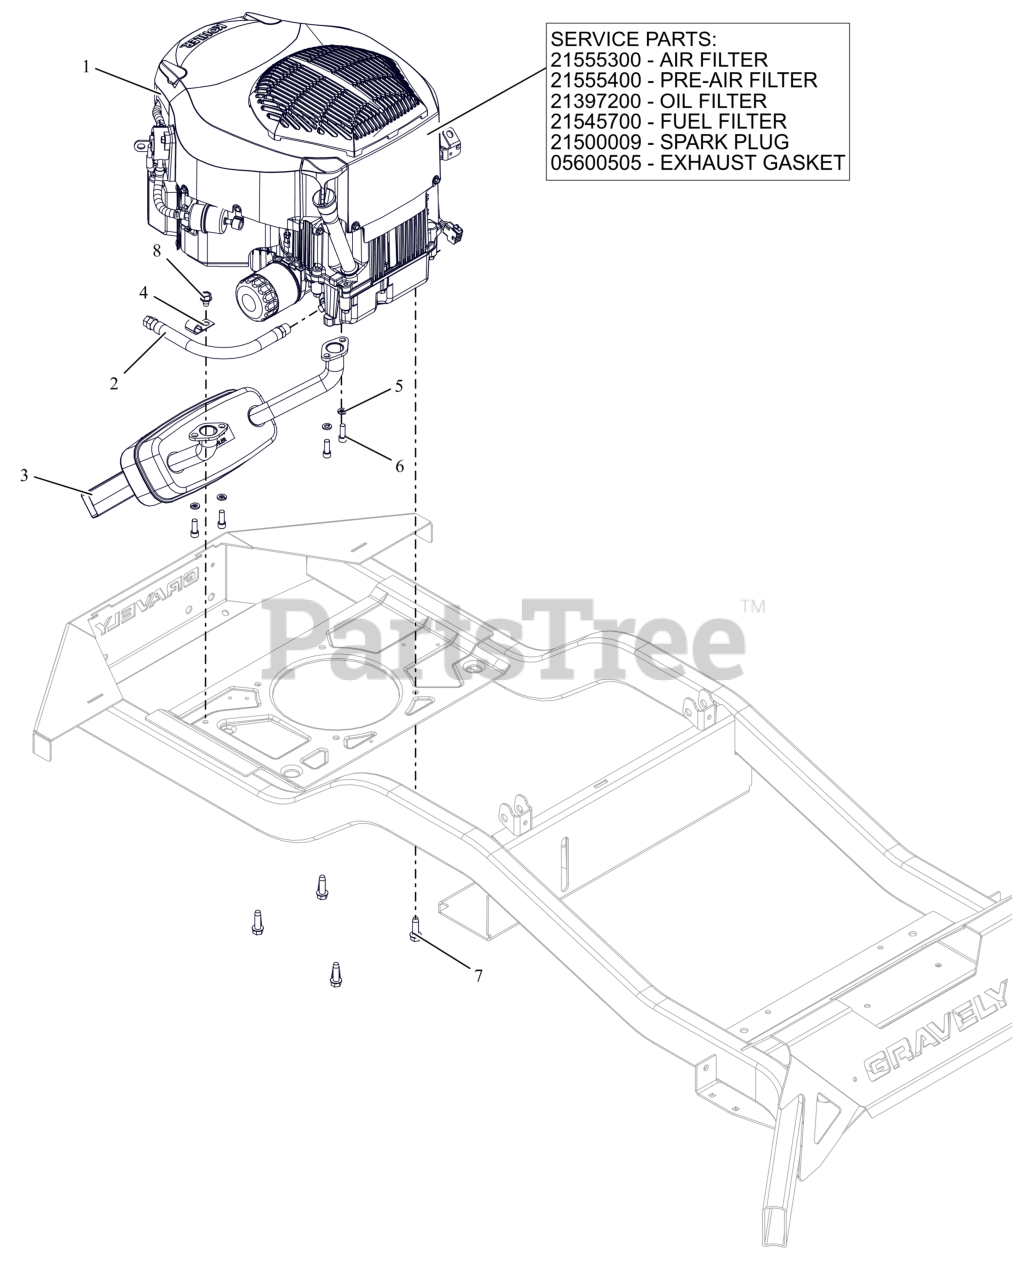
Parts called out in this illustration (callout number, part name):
1	ENGINE, KOHLER - KT745
1	AIR FILTER, KOHLER
1	PRE CLEANER, KOHLER
1	FILTER, OIL - KOH CV20
1	FILTER-FUEL KOHLER COURAGE PRO
1	PLUG, SPARK KOHLER
1	GASKET, MUFFLER KOHLER TWIN
2	HOSE, OIL DRAIN
3	MUFFLER, KOHLER
5	WSHR,LK-REG .312X.078 ZCC
6	SCR, SKH .312-18X.875 GR8 ZCC
7	SCR,TAP .375-16X1.25HWH TR ZCC
8	SCR,TAP .375-16X.50 HWH TR ZCC
